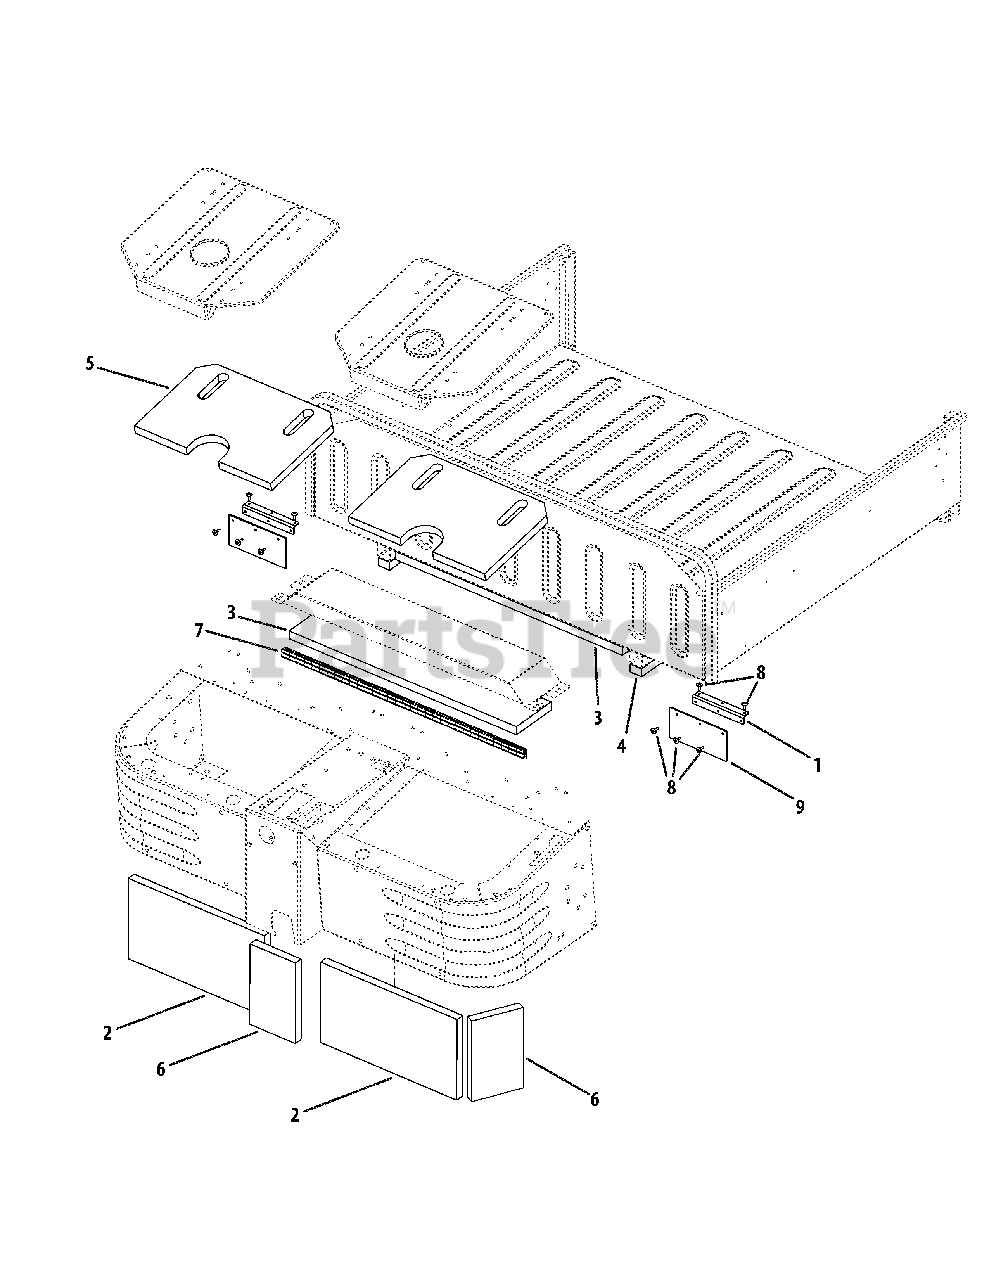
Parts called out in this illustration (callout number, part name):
1	Mud Flap Mounting Bracket
2	Acoustic Foam, 10 x 18 x 1
3	Acoustic Foam, 30 x 6 x 1
4	Acoustic Foam, 12 x 1.5 x 1
5	Acoustic Foam, Passenger Seat
6	Acoustic Foam, 10 x 6 x 1
7	Heat Baffle Seal
8	Pop Rivet, .188 dia.
9	UV Rear Mud Flap
